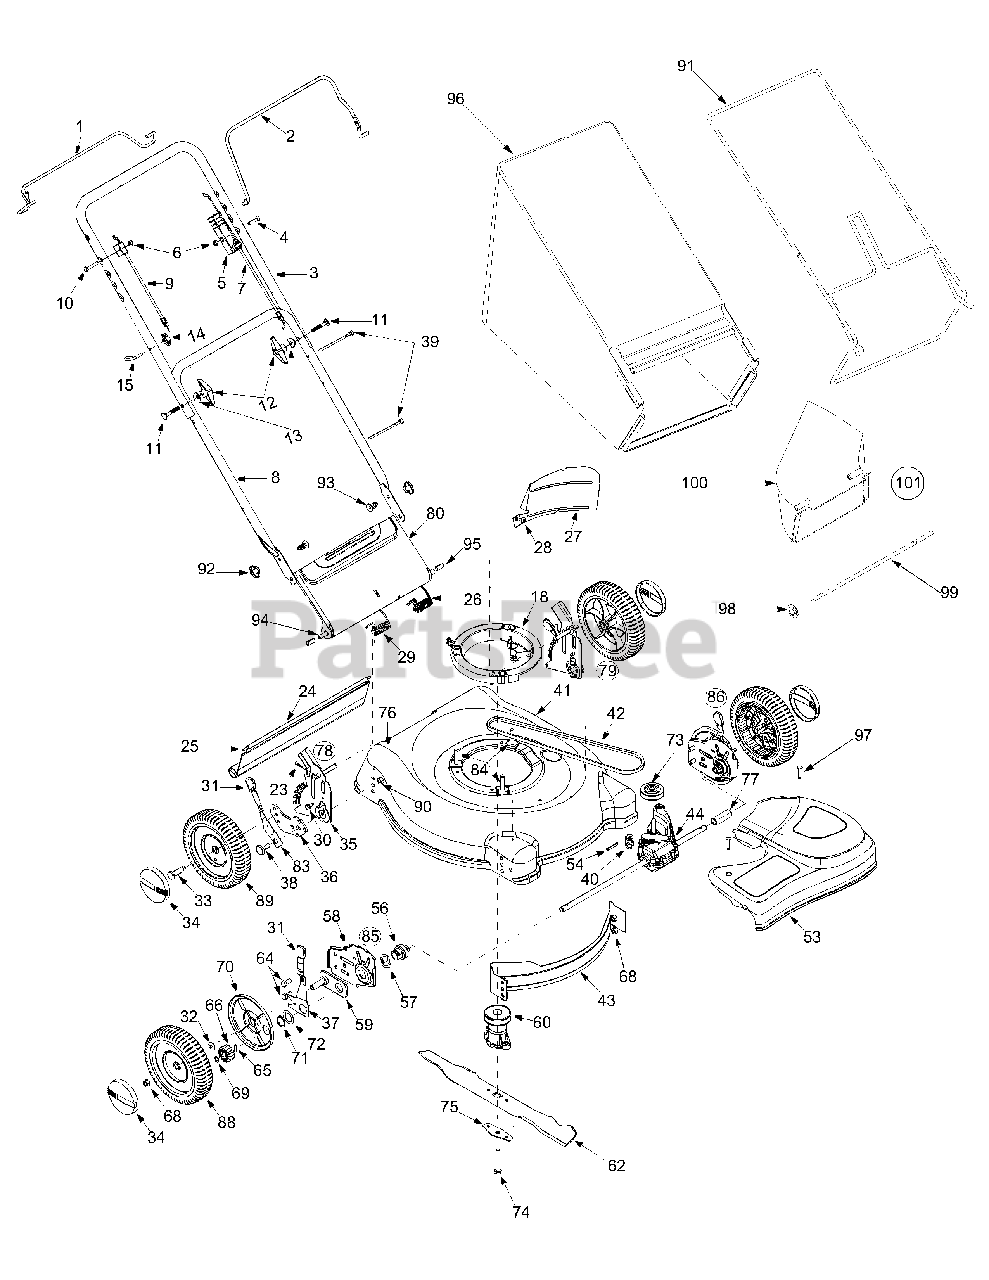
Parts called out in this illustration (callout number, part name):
5	Control Housing
6	Hex Lock Nut 1/4-20
7	Control Cable: 43"
9	Drive Cable
10	Hex Screw 1/4-20 x 1.5"
11	Carriage Bolt
12	Handle Knob
13	Saddle Washer
14	Wing Nut
15	Rope Guide
18	Engine Spacer Assembly
23	Hairpin Clip
24	Rear Trail Shield
25	Wire: Trail Shield
26	Torsion Spring LH
28	Scr. AB 1/4-14 x 0.625"
29	Torsion Spring RH
30	Hex Scr. w/ Wash. 1/4-14 x 0.62"
31	Knob
32	Bell Washer .375 x .870
33	Shoulder Screw
34	Hubcap
36	Pivot Bar LH
37	Front Lever RH
37	Front Lever LH
38	Shoulder Screw
39	Cable Tie
40	Belt Tension Spring
41	Rear Discharge Deck: 21"
42	V-Belt
53	Front Drive Cover
54	Roll Pin
56	Bearing Assembly
57	Wave Washer
60	21" One Piece Blade Adapter
62	Mulching Blade w/ Star: 21"
64	Hex Screw
65	Dowel Pin
66	Gear 14T RH
66	Gear 14T LH
68	Hex Nut
69	Snap Ring
70	Wheel Dust Cap
71	Snap Ring
72	Washer DD 1.5" O.D.
73	Input Pulley
74	Hex Bolt
75	Bell Blade Support
77	Slev. Spacer LH
77	Slev. Spacer RH
78	Handle Brkt Assembly RH Compl.
79	Handle Brkt Assembly LH Compl.
80	RD Chute Door
83	Spring Lever
84	TT Screw
85	Height Adj. Assembly RH Compl.
86	Height Adj. Assembly LH Compl.
88	Front Wheel Complete, 8x1.8
89	Rear Wheel Complete, 8X1.75
90	Hex Nut
92	Wing Nut
93	Hex Carriage Screw
94	Rear Door Pivot Rod
95	Spacer.390OD x.810ID x.950"
96	Grass Bag
97	Shoulder Screw
98	Nut: Spd.3125ID
99	Rod†
100	Side Discharge Adapter
101	Chute Deflector Complete
